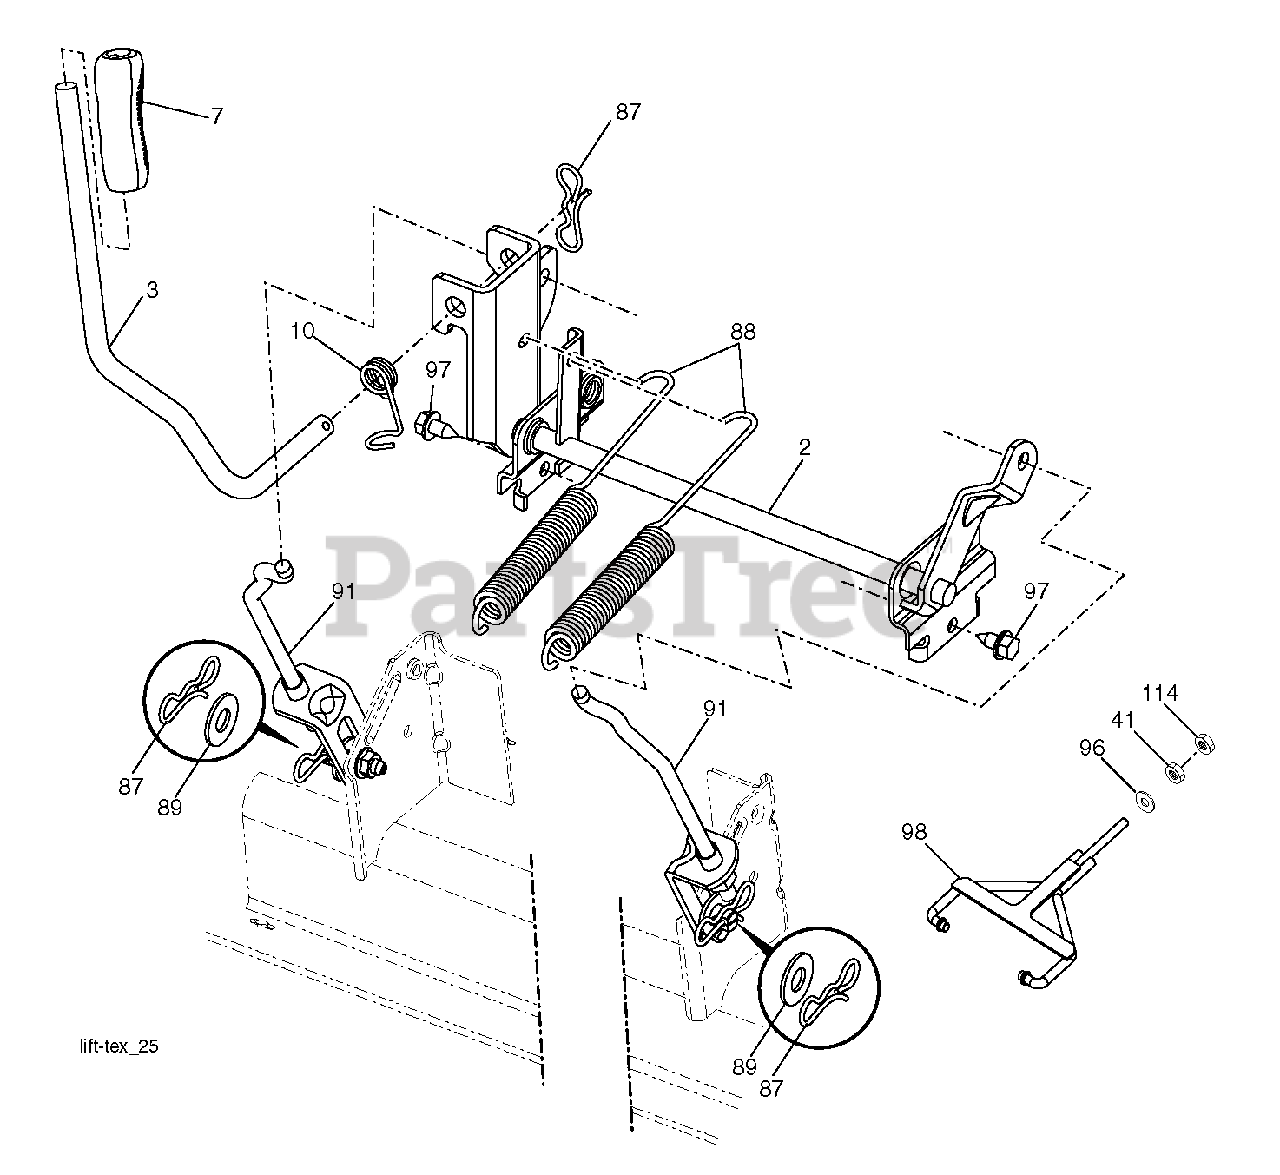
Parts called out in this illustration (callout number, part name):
2	SHAFT.ASM.CROSS.LIFT
3	LEVER.LIFT.HANDLE.GT
10	SPRING.TORSION.LIFT.HANDLE
41	NUT, LIFT LINK 7/16-20
87	PIN.COTTER.7/16.BOW TI
88	SPRING.LIFT.ASSIST.GT2
89	WASHER.CLEAR.ZINC
91	LINK.ASM.LIFT.REAR
96	BUSHING SPHERICAL SUSP. FRONT
97	SCREW, 3/8-16X3/4
98	WELDMENT.FRONT.DECK.SUSPENSION
